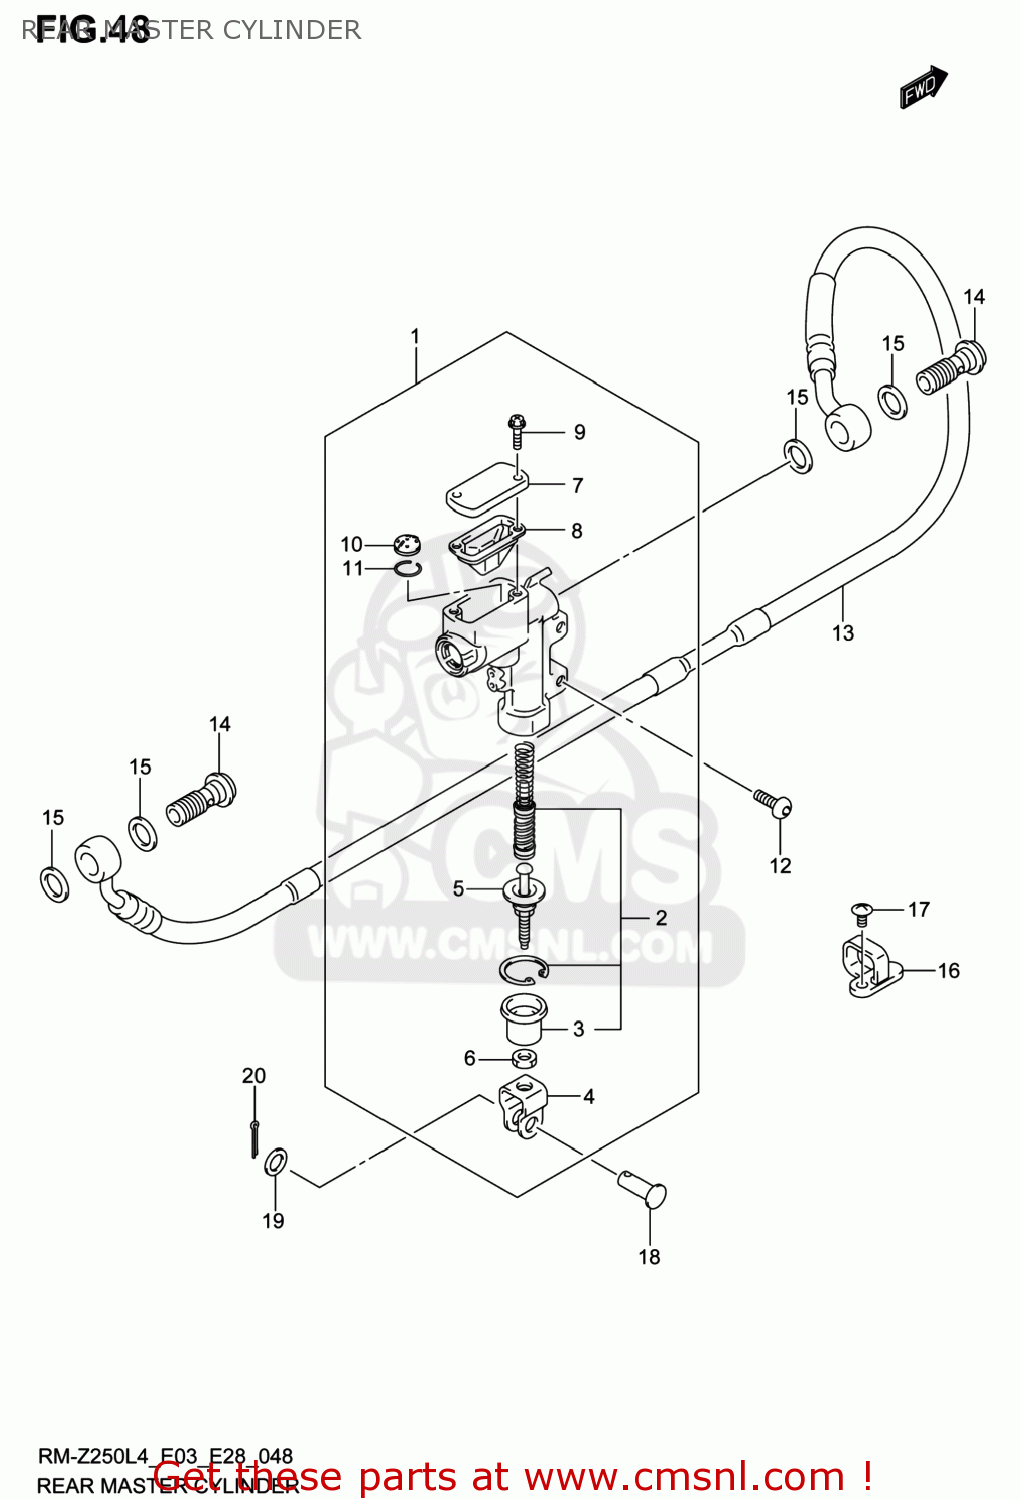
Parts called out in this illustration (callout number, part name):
1	CYLINDER ASSY,REAR MASTER
2	PISTON/CUP SET
3	BOOT
4	YOKE
5	ROD,PUSH
6	NUT
7	CAP
8	DIAPHRAGM
9	SCREW
10	SEPARATOR
11	RING
12	SCREW(6X16)
13	HOSE,RR BRAKE
14	BOLT UNION
15	WASHER(10X15X1.5)
16	GUIDE,RR BRAKE
17	SCREW
18	PIN(8X20)
19	WASHER(8.5X14X1.6)
20	PIN
